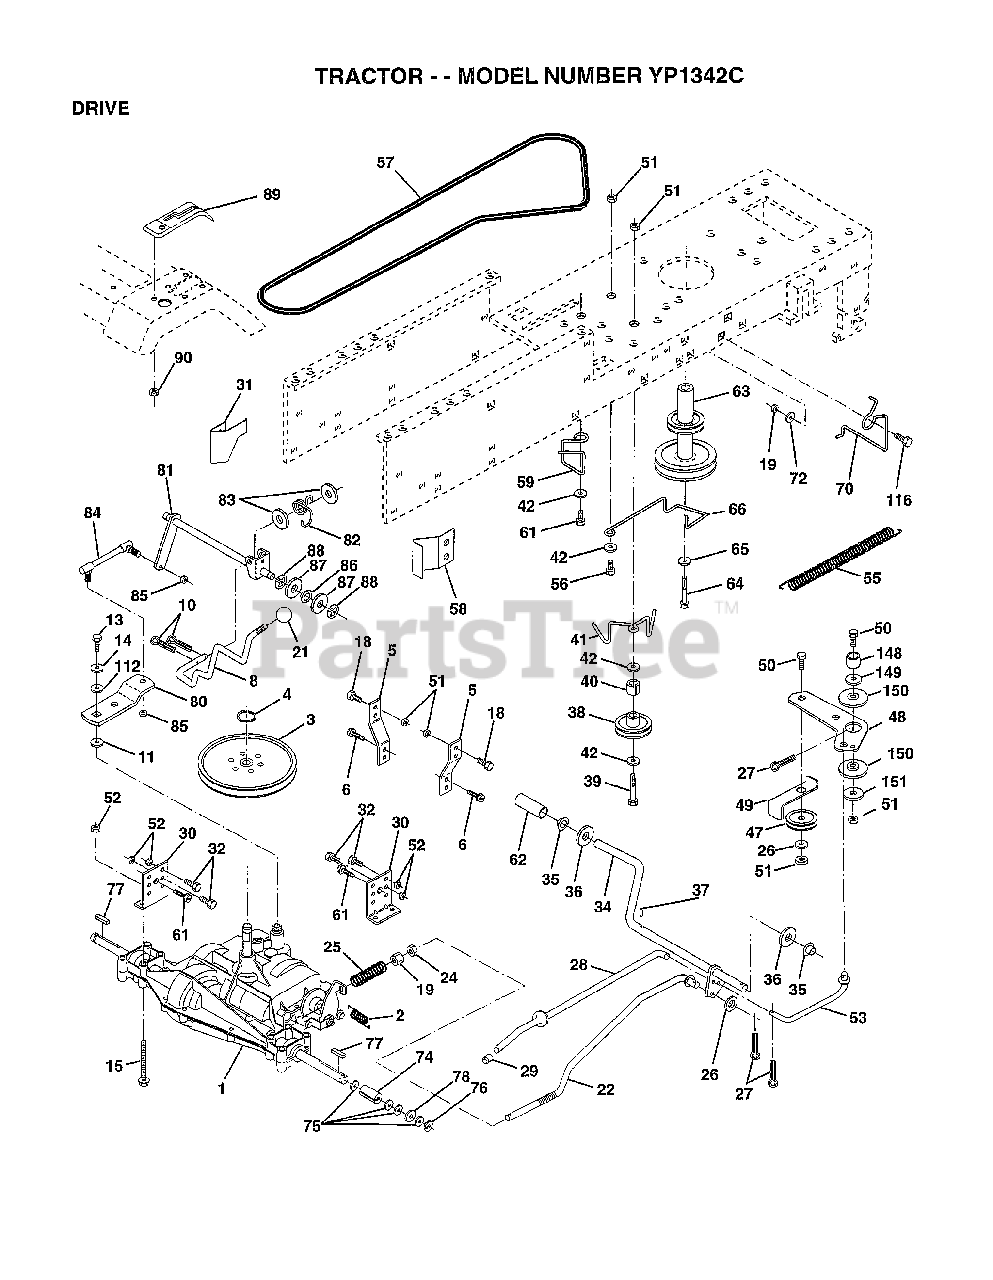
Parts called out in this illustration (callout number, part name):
2	SPRING.BRAKE.RETU
3	PULLEY TRANS
5	STRAP TORQUE
6	SCREW
8	ROD SHIFT FEND LT
10	PIN COTTER 1/8
11	WASH-SHFT PLT LT
13	BOLT.1/4-28.W/PAT
14	LOCKWASHER
15	BOLT.HX.FLG.5/16
18	BOLT
19	NUT
21	KNOB.DUCKHEAD.1/2
22	BRAKE ROD
24	NUT
25	SPRING ROD LT
26	WASHER
27	COTTER PIN
28	ROD.BRAKE.PARK.LT
29	PLUNGER CAP T
30	TRANSAXLE MTG BKT
31	"KEEPER,BELT LH T"
32	BOLT
34	SHAFT ASM-PEDAL F
35	NYLON BEARING
36	WASHER LT
38	IDLER, FLAT
39	BOLT
40	SPACER T
42	WASHER
48	BELLCRANK.CLUTCH
49	RETAIN BELT
53	"LINK, CLUTCH T"
55	"SPRING, RETURN LT"
58	"KEEPER,BELT RH T"
59	KEEPER BELT CNTSP
61	SCREW
62	PEDAL COVER T
63	PULLEY.ENGINE
64	BOLT
65	LOCKWASHER
66	KEEPER-BELT
72	WASHER
74	SPACER LT
76	E-RING LT
77	SQUARE KEY
78	WASHER
80	SHIFT LEVER
81	SHAFT.CROSS
82	"SPRING,TORSION"
83	WASHER
84	TIE ROD
85	NUT.CNT.LOCK.1/4
86	BUSHING
87	WASHER D
88	KLIP RING
90	NUT
112	WASHER LT
116	BOLT RDHD 3/8-16
149	SPACER RETAINER
150	BUSHING.NYLON
151	WASHER
